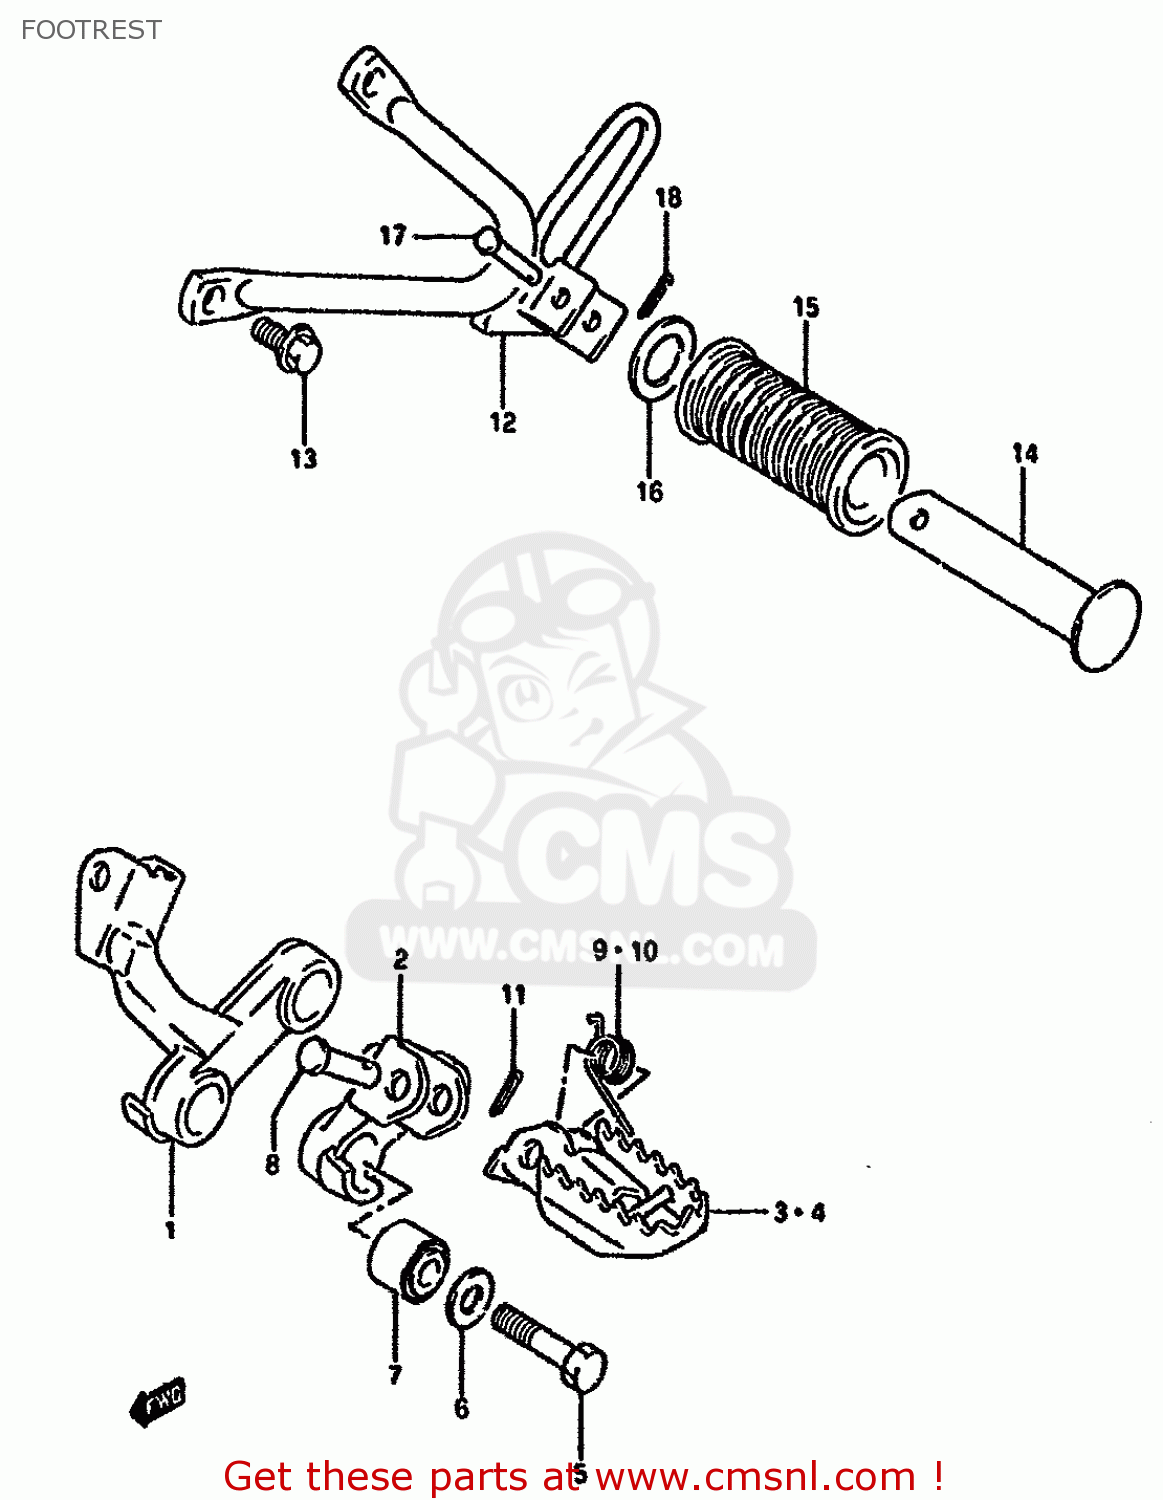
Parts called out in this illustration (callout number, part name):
1	BRACKET,FOOTRS
2	BRKT,FR FTRST,
3	FOOTREST COMP,FRONT,RIGHT
4	FOOTREST COMP,FRONT,LEFT
5	BOLT(10X45)
6	WASHER
7	BUSH(10.2X25X19)
8	PIN
9	SPRING
10	SPRING
11	PIN 20X20
12	BRACKET,PILLION FOOT,R(BLACK)
13	BOLT
14	BAR,FOOTREST RUBBER
15	RUBBER,PILLION FOOTREST
16	WASHER (19.5X32X2)
17	PIN
18	PIN 20X20
